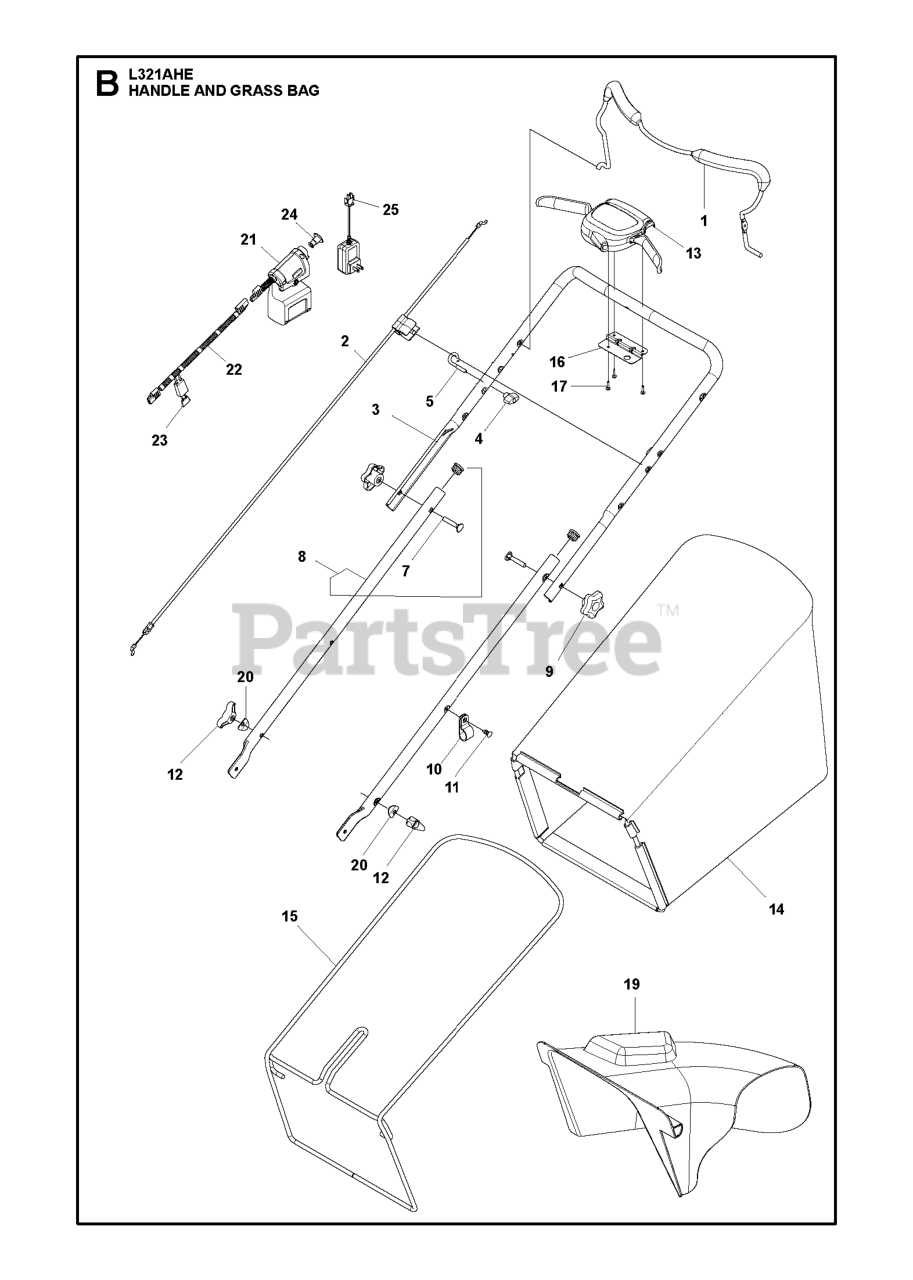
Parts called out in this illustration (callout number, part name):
1	BAIL CURVED, OPC, KOHLER E-STA
2	CABLE.MZR.50.SNAP-IN
3	HANDLE.UPPER.3.POS.BS.AW2.GREY
4	T-KNOB.NEW ROPE GUIDE
5	GUIDE.ROPE.BLK.ZINC.CHROM
7	BOLT.CONCAVE.HEAD.RETAINING
8	HANDLEBAR ASSY TWO PIECE LOWER
9	KNOB.HANDLE.PLASTIC.STAR.BLACK
10	CLIP.CABLE.BLK
11	FASTENER.PUSH.O.250X0.783
12	KNOB, DEFLECTOR
13	CONTROL.AW2.GEN.CURVED.AW/RGD.
14	GBAG.C361029EM.HUSQ.GRY.21EFF
15	FRAME.GBAG.AWD.21.BLACK
16	BRACKET DUAL TRIGGER CONTROL
17	SCREW, PHILLIPS HEAD 10 X 5/8
19	CHUTE.DISCHARGE.21EFF.HW
20	WASHER CURVED 5/16"X1"X0.06" S
21	STARTER SYSTEM MODULAR E-START
22	WIRING ASSY E-START MODULE, MO
24	BUTTON.KEY.CYLINDER.BLACK
25	CHARGER.BATT.12V LEAD-ACID.DOM
